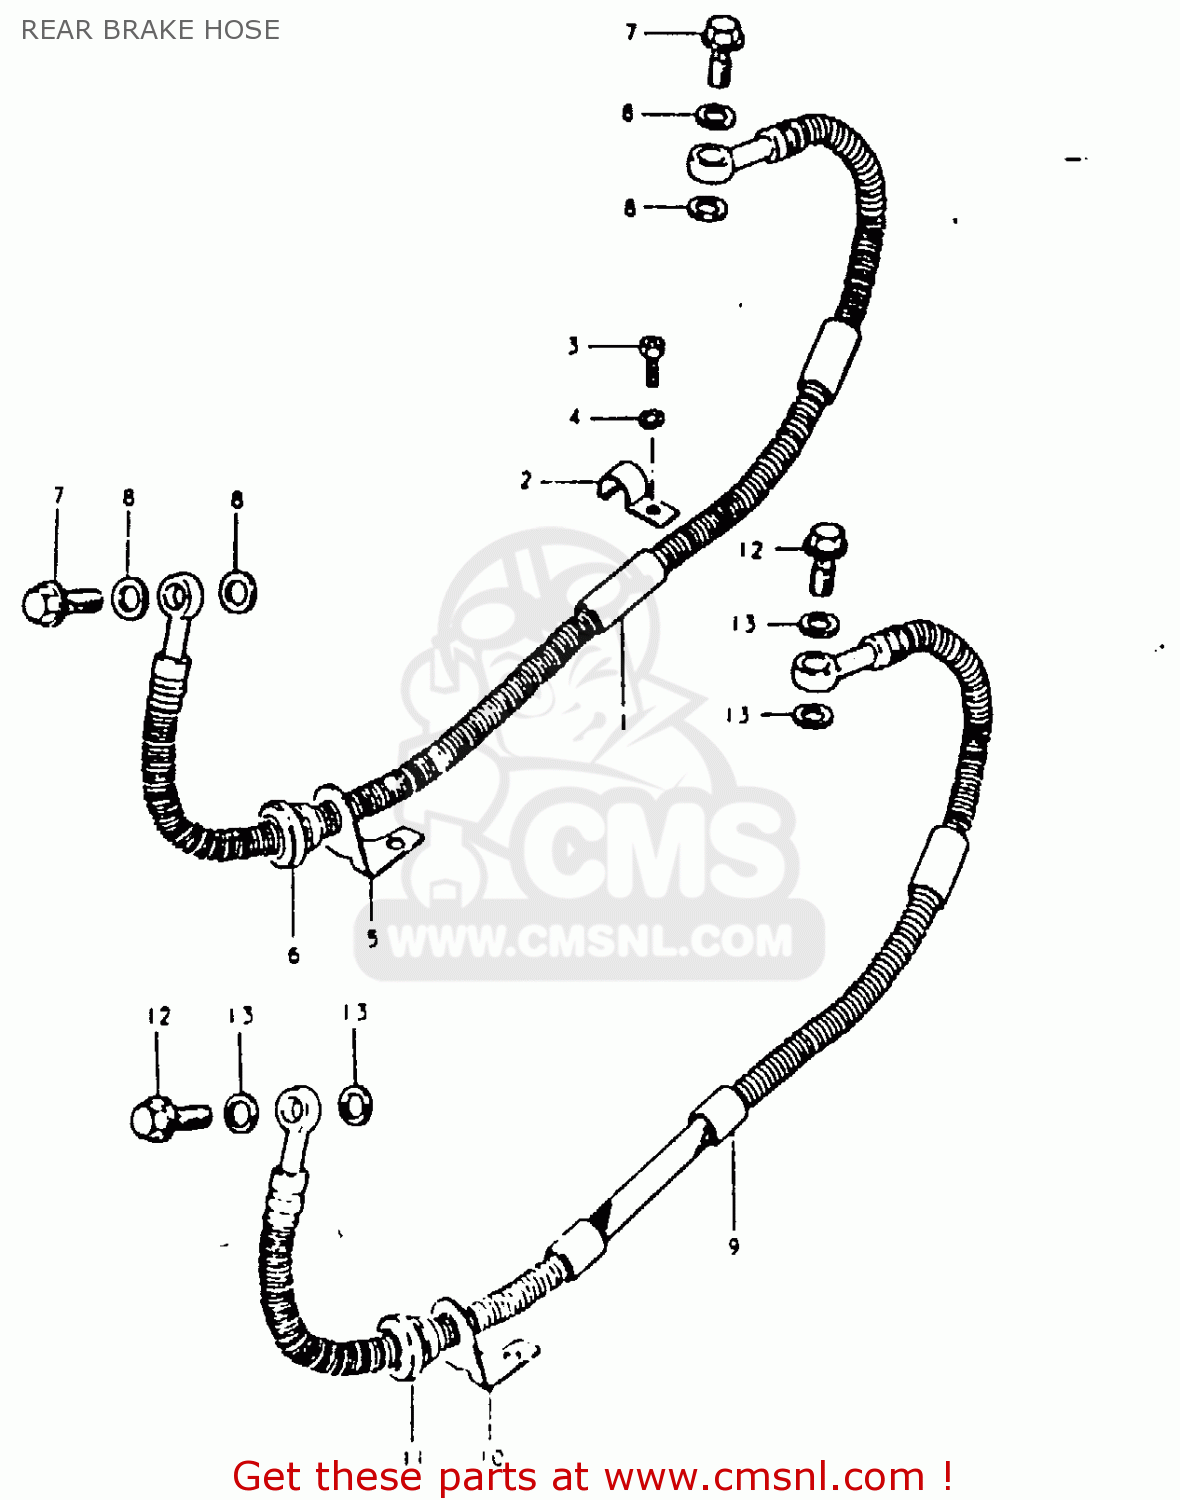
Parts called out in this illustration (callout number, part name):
1	HOSE,REAR BRAKE
2	CLAMP,REAR BRAKE HOSE
3	SCREW(6X8)
4	LOCK WASHER
5	GUIDE,BRAKE HOSE
6	GROMMET,BRAKE HOSE GUIDE
7	BOLT,UNION
8	WASHER
9	HOSE,REAR BRAKE
10	GUIDE,BRAKE HOSE
11	GROMMET,BRAKE HOSE GUIDE
12	BOLT UNION
13	WASHER
